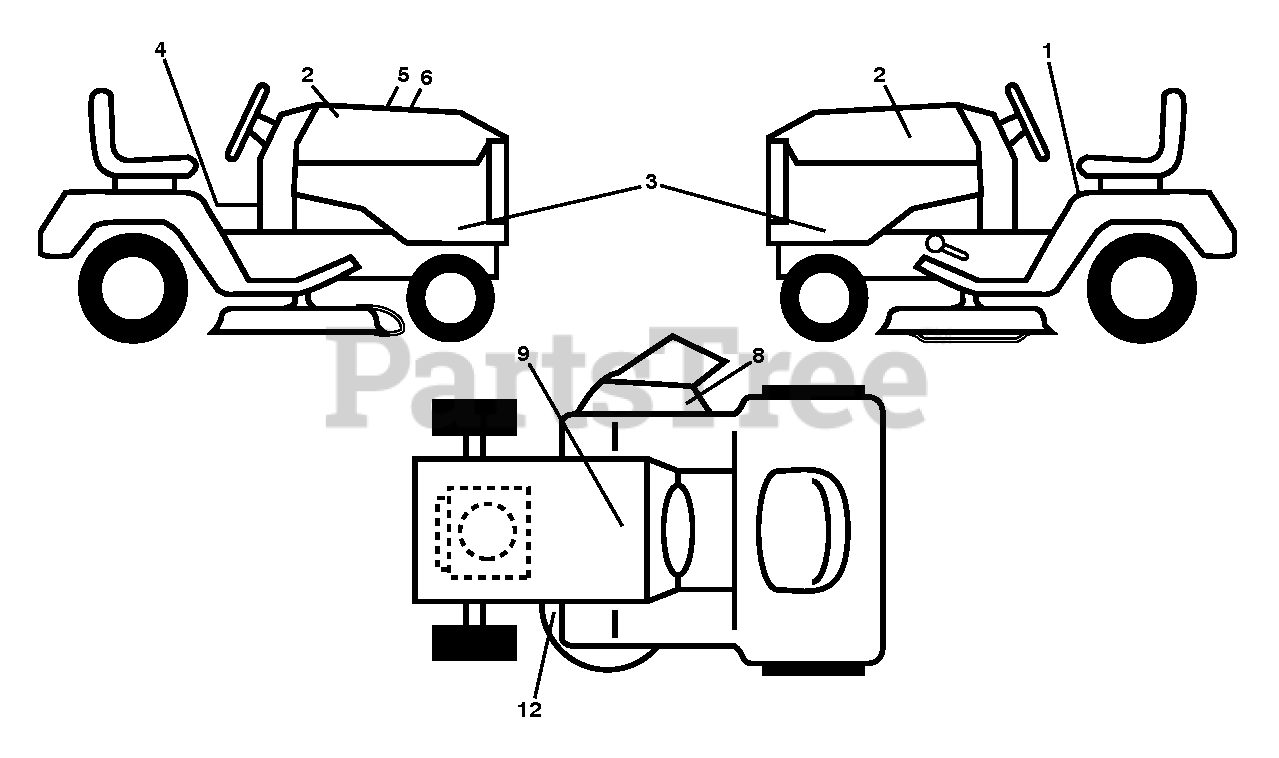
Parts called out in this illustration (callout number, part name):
1	DECAL.FENDER.WARNING
2	RP.DECAL.BADGE.170MM.TEXTLOGO
3	DECAL.SDPNL.HUSQGT2.YTH12K26.2
4	DECAL, WARNING SPARK ARRESTOR
5	DECAL.WARNING.CUST.RESP.E85.
8	DECAL.WARN.KEEP.HAND.AWAY
9	DECAL BTRY SYMBOLS
12	DECAL V BELT SCHEMATIC
